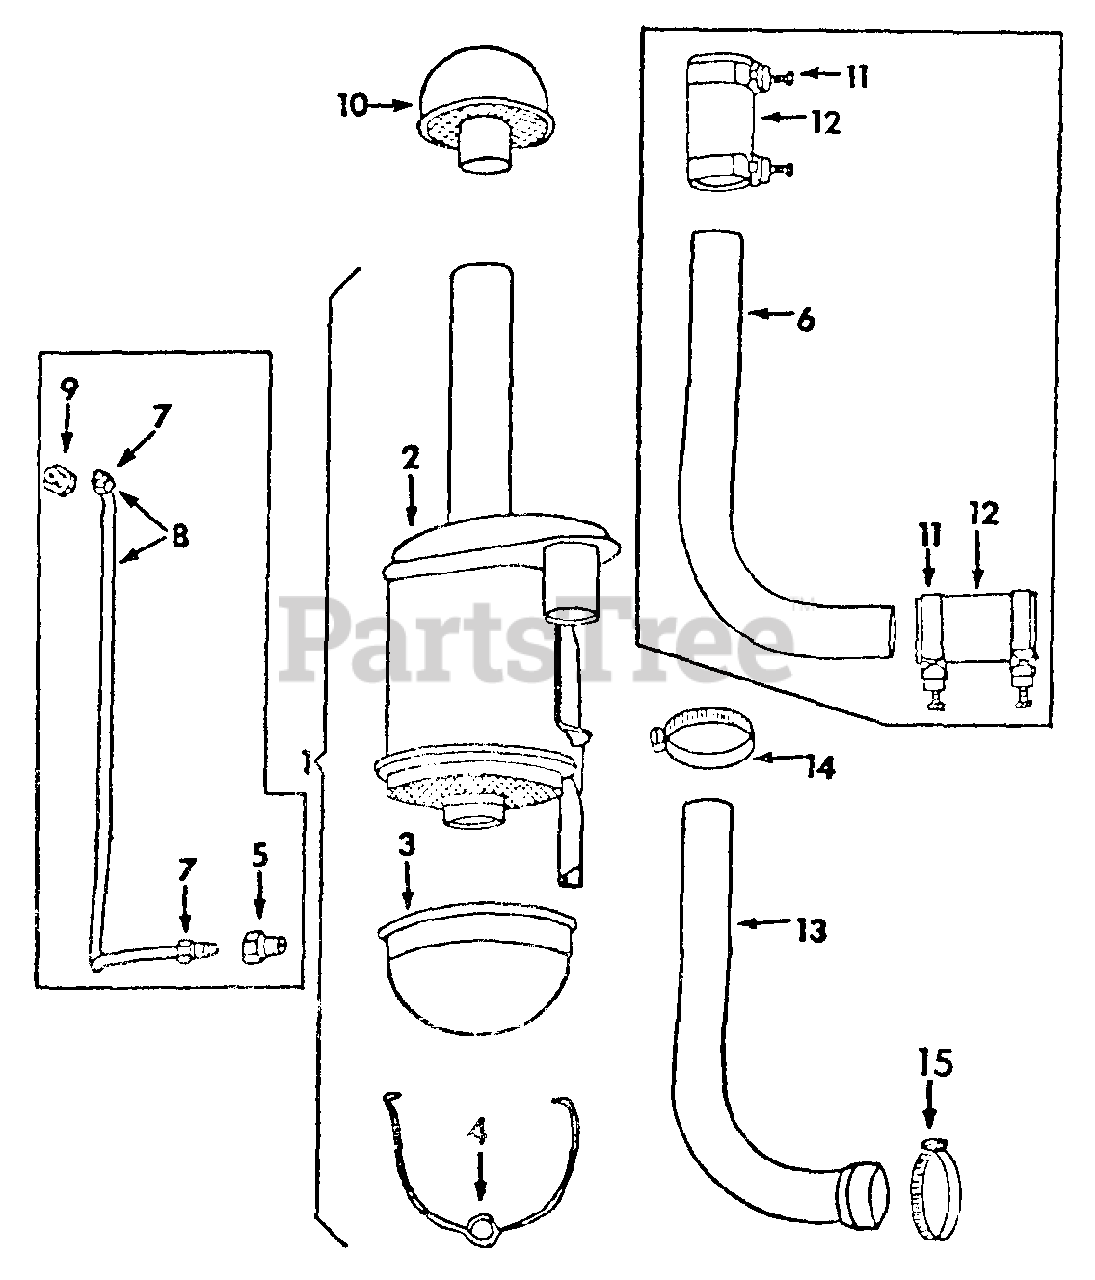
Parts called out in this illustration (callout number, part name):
1	CLEANER ASSY, AIR
2	BODY, AIR CLEANER
3	CUP, AIR CLEANER OIL
4	CLAMP, AIR CLEANER CUP RETAINING
5	CONNECTOR, BREATHER PIPE
6	PIPE, AIR CLEANER
7	NUT, BREATHER PIPE CONNECTOR
8	PIPE
9	COUPLING, BREATHER PIPE
10	CAP, AIR INTAKE
11	CLAMP AIR CLEANER PIPE HOSE
12	HOSE, 1-1/4 ID X 2-1/2 IN LONG, 3 PLY AIR CLEANER PIPE
13	HOSE, AIR CLEANER TO CARBURETOR
14	CLAMP, HOSE -AIR CLEANER END
15	CLAMP, HOSE -CARBURETOR END
